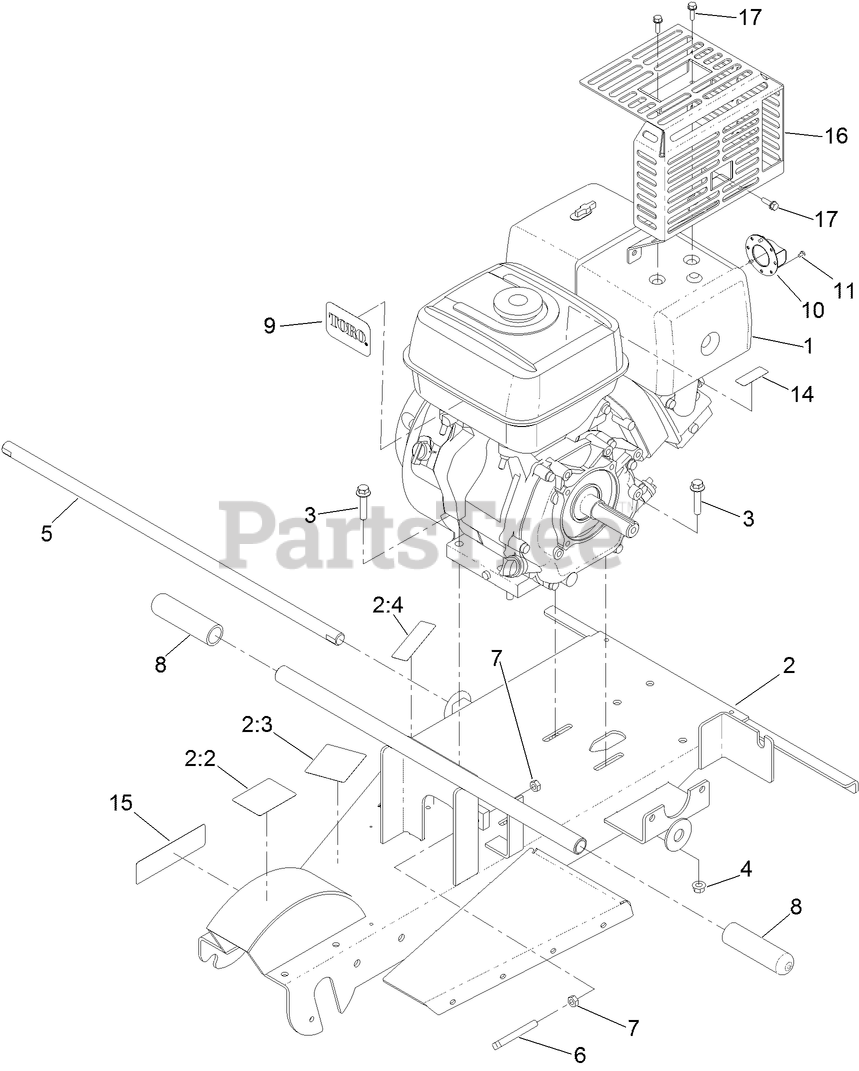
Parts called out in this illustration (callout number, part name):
2	FRAME ASM
2:2	DECAL-DANGER
2:3	DECAL-CAUTION
2:4	DECAL-ARRESTER, SPARK
3	SCREW-HHF
4	NUT-HF
5	BAR-AXLE
6	SCREW-SET, SQH
7	NUT-HEX
8	GRIP-HANDLE
9	DECAL
10	DEFLECTOR-EXHAUST, HONDA
11	SCREW-SELF TAPPING
14	DECAL-WARNING, ETHANOL
15	DECAL-ROTATE TOOTH
16	GUARD-MUFFLER, [BLACK]
